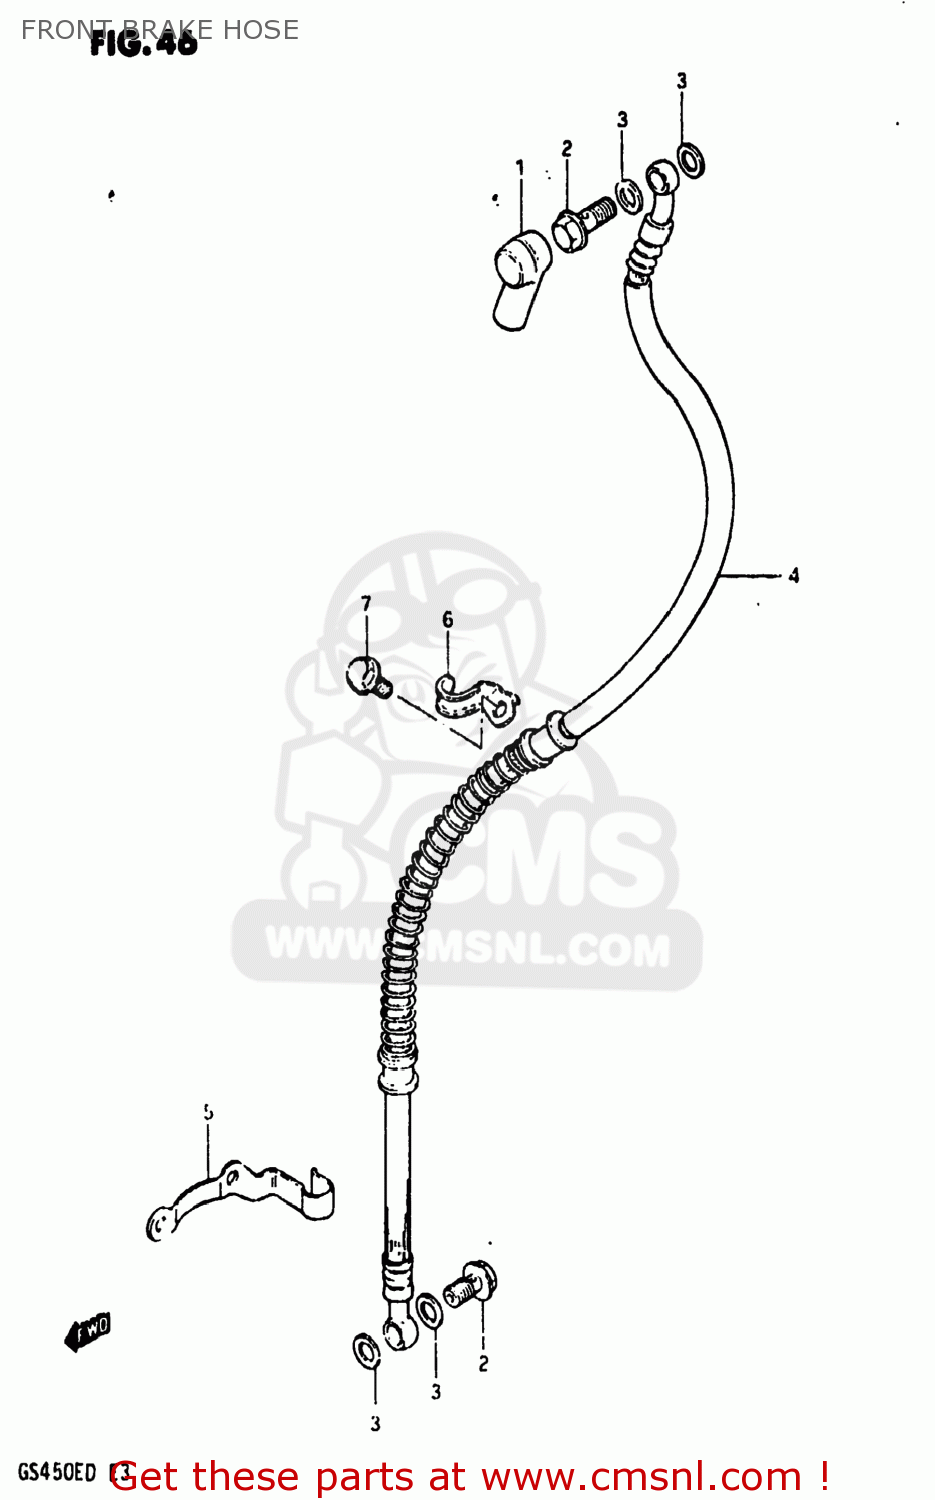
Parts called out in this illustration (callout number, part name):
1	BOOT,MASTER CYLINDER
2	BOLT,UNION
3	WASHER
4	HOSE,FR BRAKE
5	CLAMP,FRONT BRAKE HOSE
6	GUIDE,BRAKE HOSE NO.3
7	BOLT
